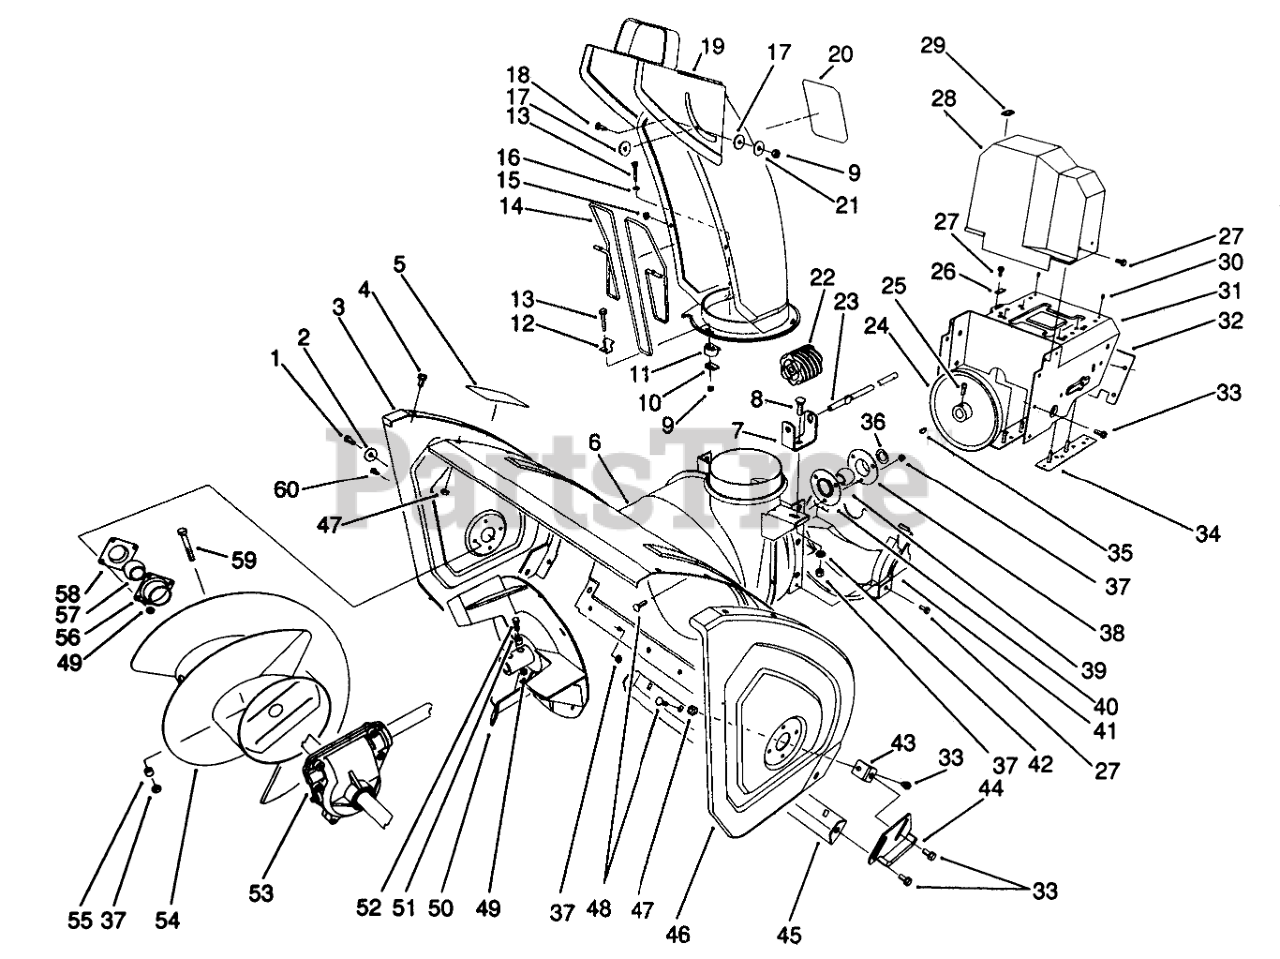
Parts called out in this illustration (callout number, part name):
1	SCREW-HH
2	WASHER
3	PLATE-SIDE, RH
4	SCREW-HHF
5	DECAL-WARNING, AUGER
6	Housing-24"
7	BRACKET-WORM, CHUTE
8	BOLT-CARR
9	NUT-LOCK, NI
10	PLATE-RETAINER, CHUTE
11	RETAINER-CHUTE
12	CLIP-GUARD, CHUTE
13	SCREW-HSH
14	GUARD-CHUTE
15	NUT-PUSH
16	WASHER-FLAT
17	WASHER-PLASTIC
19	Assembly
20	DECAL-DANGER DISCH.
21	WASHER-FLAT
22	GEAR-WORM
23	ROD-CHUTE, LOWER
24	PULLEY-IMPELLER
25	SCREW-SET, SQH
26	RETAINER-CABLE
27	SCREW-HWH
28	COVER-BELT, UPPER
29	COVER-CABLE
30	RIVET-POP
31	Frame-Engine
32	Cover-Frame, Engine
33	SCREW-HHF
34	LH FRAME PLATE ASM
35	KEY-WOODRUFF
36	WASHER-THRUST
37	NUT-LOCK, NI
38	Flange-Bearing (Rear)
39	BEARING-BALL
40	Flange-Bearing (Front)
41	Cover-Belt (Lower)
42	WASHER-PLAIN
43	Bracket-Skid
44	SKID WA
45	Blade-Scraper
46	Plate-Side LH
47	NUT-LOCK, NI
48	SCREW-CARR
49	NUT-LOCK, NI
50	Impeller
51	SPACER
52	SCREW-HHF
53	Auger Gearbox Assembly
54	Auger-R.H.
55	SPACER-HUB, AUGER
56	BEARING-FLANGE, FRONT
57	BEARING
58	BEARING-FLANGE, REAR
59	Auger Bolt
60	SCREW-HH
